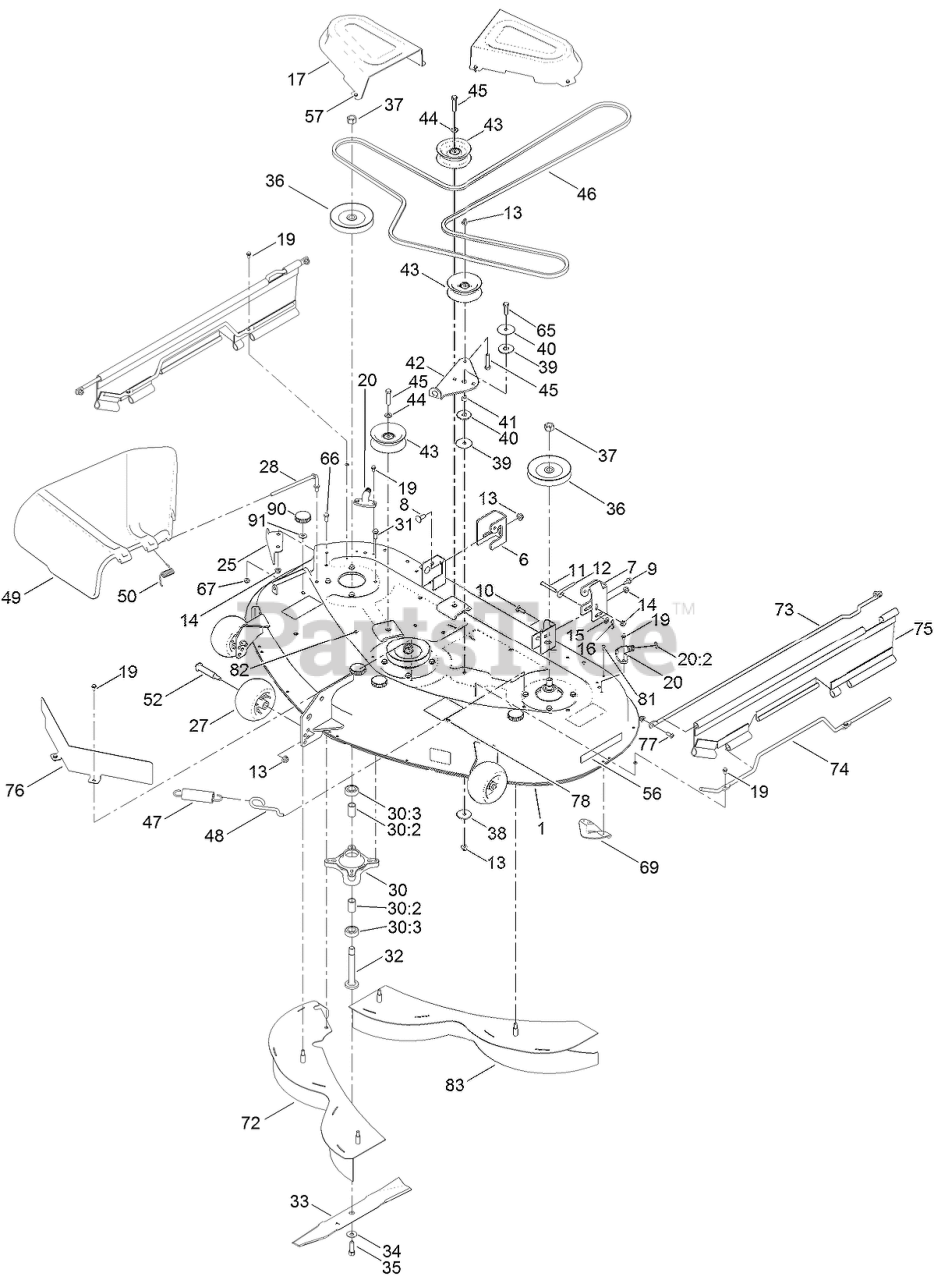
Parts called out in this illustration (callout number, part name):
1	50 INCH DECK AND DECAL ASM
6	BRACKET-HANGER, RH
7	BRACKET-HANGER, LH
8	BOLT-CARR
9	SCREW-SHOULDER,HWH
10	SCREW-CARR
11	PIN-CLEVIS
12	ROD-LEVEL, DECK
13	NUT-HF, NI
14	NUT-HF, NI
15	WASHER-PLAIN
16	PIN-COTTER
17	COVER-BELT
19	SCREW-HWH
20	FITTING-WASHOUT
20:2	O-RING
25	BAFFLE-CUTOFF
27	ROLLER-SCALP, ANTI
28	ROD-PIVOT
30	SPINDLE ASM
30:2	SPACER
30:3	BEARING-BALL
31	SCREW-TAPTITE
32	SHAFT-SPINDLE
33	BLADE-MULCH, 17.50 INCH
34	WASHER-BELLEVILLE
35	SCREW-HH
36	PULLEY
37	NUT-HEX
38	WASHER-REBOUND
39	WASHER
40	WASHER-FRICTION, COMPOSITE
41	SPACER
42	ARM-IDLER
43	PULLEY-IDLER, FLAT
44	WASHER-FLAT
45	SCREW-HH
46	V-BELT
47	SPRING-EXTENSION
48	HOOK-RETURN, SPRING
49	DEFLECTOR
50	SPRING-TORSION
52	BOLT-SHOULDER
56	DECAL-RECYCLER
57	SCREW-TAPTITE
65	SCREW-HH
66	SCREW-HH
69	PLATE-KICKER
72	RH BAFFLE ASM
73	ROD-SUPPORT, UPPER
74	ROD SUPPORT, LOWER
75	GUARD-SIDE
76	SHIELD-FRONT
77	SCREW-HSBH
78	NUT-RETAINING
81	SCREW-PPH
82	NUT-RETAINING
83	LH BAFFLE ASM
91	WASHER-BELLEVILLE
